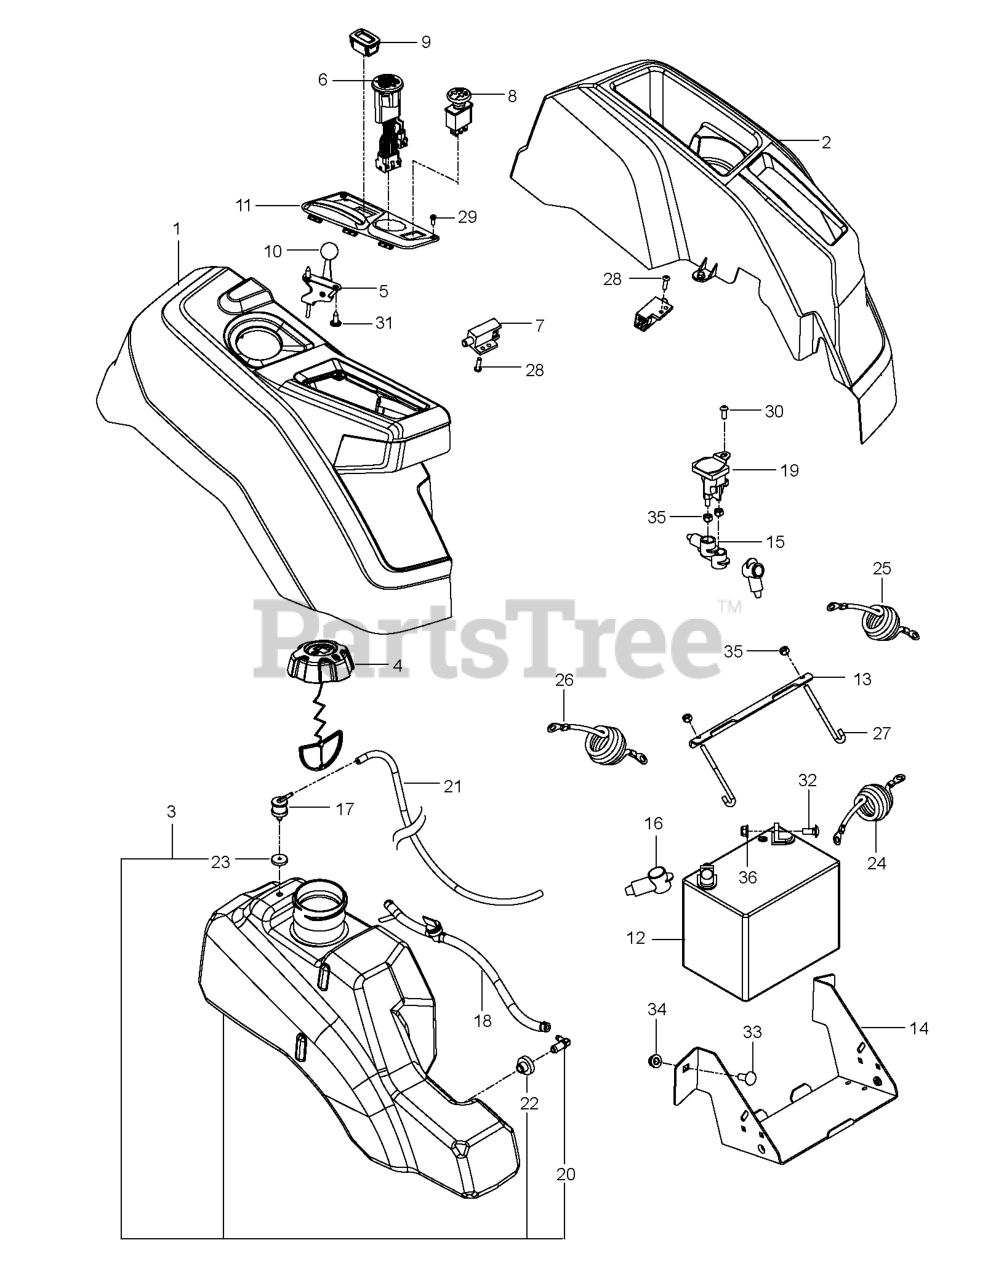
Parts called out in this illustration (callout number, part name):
1	HANDLE.ASM.UPPER.W/GRIP
2	CABLE.MZR.50.SNAP-IN
3	BRACKET.UPSTOP.RT
6	KNOB.HANDLE.PLASTIC.STAR.BLACK
8	BAIL.CONTROL.MZR.BS.ORANGE
9	DOOR.REAR.ASM.22+.HUSQ.FG/RGD
11	COTTER.HAIRPIN.DOOR/HANDLE.PIV
12	KNOB, DEFLECTOR
13	PLUG.PLASTIC.7/8".14-20.GAUGE
17	RP.BAFFLE.REAR.22+.RGD.PL
18	NUT
19	RB GUIDE.ROPE.STD.BLK.ZIN WSL
20	SKIRT.REAR.22+RGD.HIGH WHEEL
21	SPRING.LH.BLACK
22	SCREW.PAN.HEAD.#10
24	SPRING.RH.GRAY
26	SCREW,DOOR/HANDLE.PIVOT
28	BOLT
30	GBAG.B5610247T.SIL.HUSQ.BLUE
31	RB FRAME.GBAG.22PLUS
32	LATCH.DOOR.ZINC
33	DOOR.MULCH.22 PLUS.HUSQ.GREY
34	BRACKET.GRASSBAG.ATTACHING.BLK
36	BRACKET.ASM.HINGE.21.FWGD.
37	BOLT.5/16HEX.WHS.HD
38	DEFLECTOR.CLIPPING.22.BLACK
39	BRACKET.HANDLE.LT.22+.W/DP.GRE
40	RP.BRACKET.ASM.HANDLE.RT.22+.
41	BOLT 3/8-16X1-1/8
42	SPRING.TORSION
43	NUT.HEX.FLANGE.1/4
44	HOUSING.22+.RWD.WO/PORT.ORANGE
45	ROD.HINGE.21
46	ADPTER.BLAD.25M.VS.22PLU.STAR
47	BLADE.22+.4.N.1
48	WASHER,HARDEN
49	LOCKWASHER
50	SCREW, HEX HD 3/8-24 X 1-3/8
51	BAFFLE.FRONT.22PLUS.PLASTIC RP
52	DANGER DECAL
53	SCREW.HI-LO.5/16 X.75
56	SCREW.HX.13X.750
57	NUT.FLANGE.5/16
58	HANDLE.LOWER.22+BT.2PC.GRY
59	BOLT, HANDLE 5/16-18X1.75
62	BRACKET.ENG/BELTKEEPER
70	GRIP.HANDLE.FOAM.WIDE.(1 SIDE)
83	TAPPING SCREW
84	FASTENER.PUSH.O.250X0.783
85	BRACKET.SKIRT.22+.BZP
96	CLIP.CABLE.BLK
97	BRACKE.BELT.GUIDE.22+
99	COVER.ASM.FRONT.SHROUD.HUSQ.
